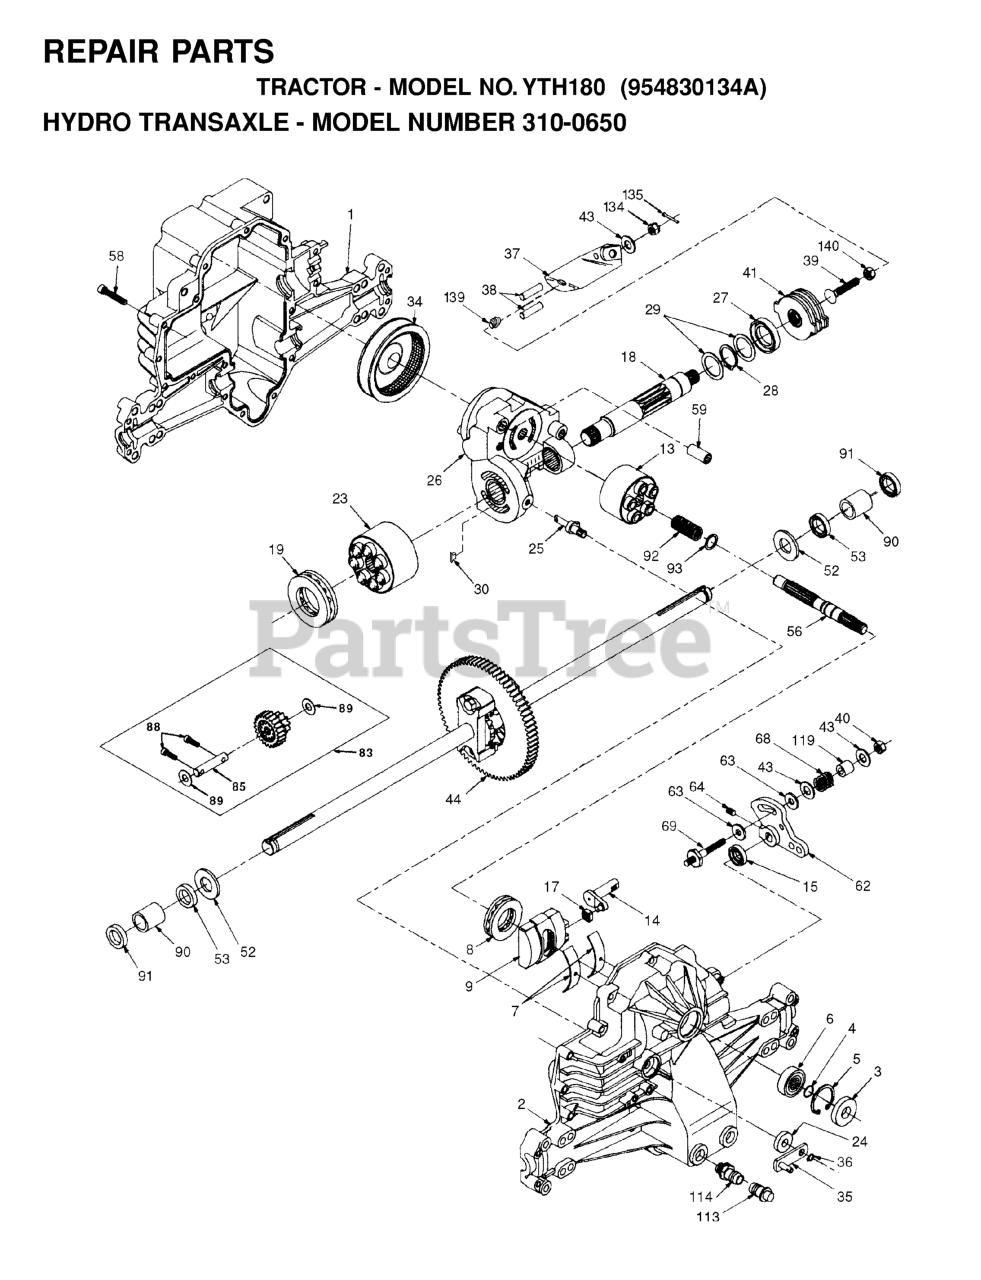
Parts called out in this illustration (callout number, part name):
1	LOWER HOUSING
2	HOUSING UPPER 70255
3	SEAL.LIP.H-G.(9008000-0128)
4	RING RETAINING 2003016
5	RING.RETAINING.(2003052)
6	BALL BEARING
7	CRADLE BEARING
8	BEARING, THRUST 50551
9	SWASHPLATE (2003087)
13	BLOCK, CYL ASSY
14	TRUNNION ARM
17	SLOT GUIDE
18	SHAFT, MOTOR
19	BEARING, THRUST 50552
23	BLOCK, CYL ASSY
25	BYPASS ACTUATOR
26	CENTER SECTION ASS'Y KIT
28	RETAINING RING
34	ELEMENT, OIL FILTER
35	BYPASS ARM
36	RETAINING RING 44870
37	ACTUATING ARM
38	ACTUATING PIN 44891
39	BOLT 5/16-24 X 1-3/4
40	LOCKNUT, HEX 5/16-24
41	BRAKE ROTOR 70135 HYDRO-GEAR
43	WASHER .34X.88X.06.44130
44	KIT SVC DIFFRENTIAL 70130
52	WASHER.HYDRO-GEAR 44875
53	SEAL.HYDRO.53901
56	SHAFT.INPUT.50005
58	BOLT #44876
62	CONTROL ARM 50254
63	DAMPENER PUCK
64	SCREW.SET.50018
68	SPRING HELICAL COMP 50277
69	STUD 5/16-24 50284
83	JACK SHAFT ASSY
89	WASHER 50132
90	SLEEVE.BEARING 50118
91	RP SEAL, WIPER
92	SPRING 2003014
113	CAP, VENT ASSY
114	O-RING KIT 70110
119	SPACER.HYDRO GEAR 50278
134	NUT.CAS.HYD.44142
135	ID DOT HYDD
139	SPRING, COMPRESSION 50431
140	NUT, HEX 5/16-24
